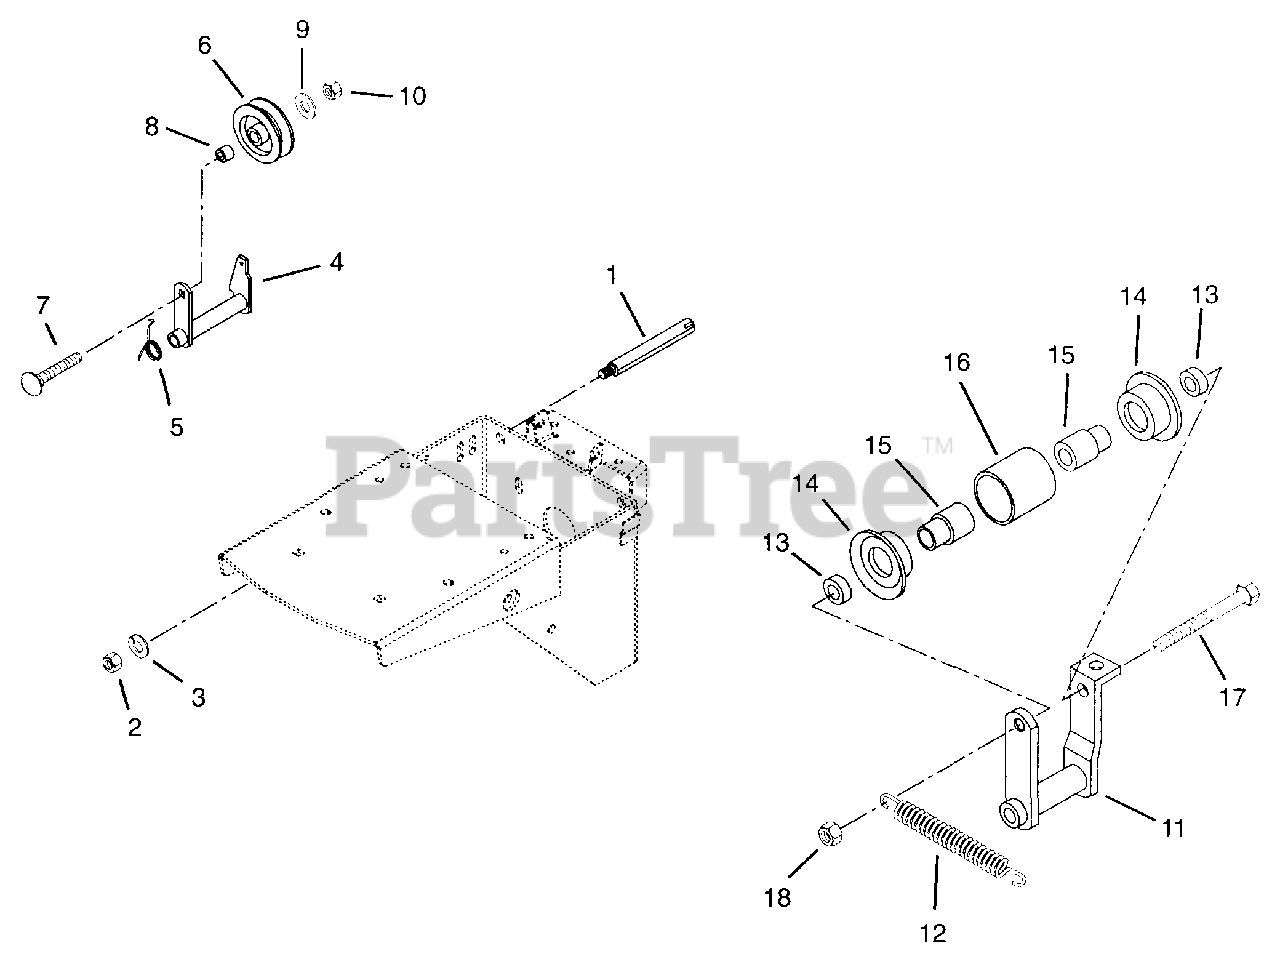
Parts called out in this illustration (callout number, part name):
1	IDLER PIN
2	@NUT-HEX .38-16 YWZC
3	@WSHR-LK .38X.094 REG YWZC
4	ARM, REVERSE IDLER
5	SG-TORS
6	IDLER
7	@BLT-HEX .31-18X1.25 GR5 YWZC
8	SPCR, BRG .315X.50X.688X.281
9	@WSHR-FL-STL.38X.875X.083 YWZC
10	NUT-HEX .312-18
11	IDLER ARM
12	SG-TENS .063X.44X2.81 WLD 18
13	BSHG, SPCR.500X.750X.321 PM
15	BEARING SPACER
17	@BLT-HEX .31-18X4.00 GR5 YWZC
18	@NUT-LK-CTR .31-18 YWZC
